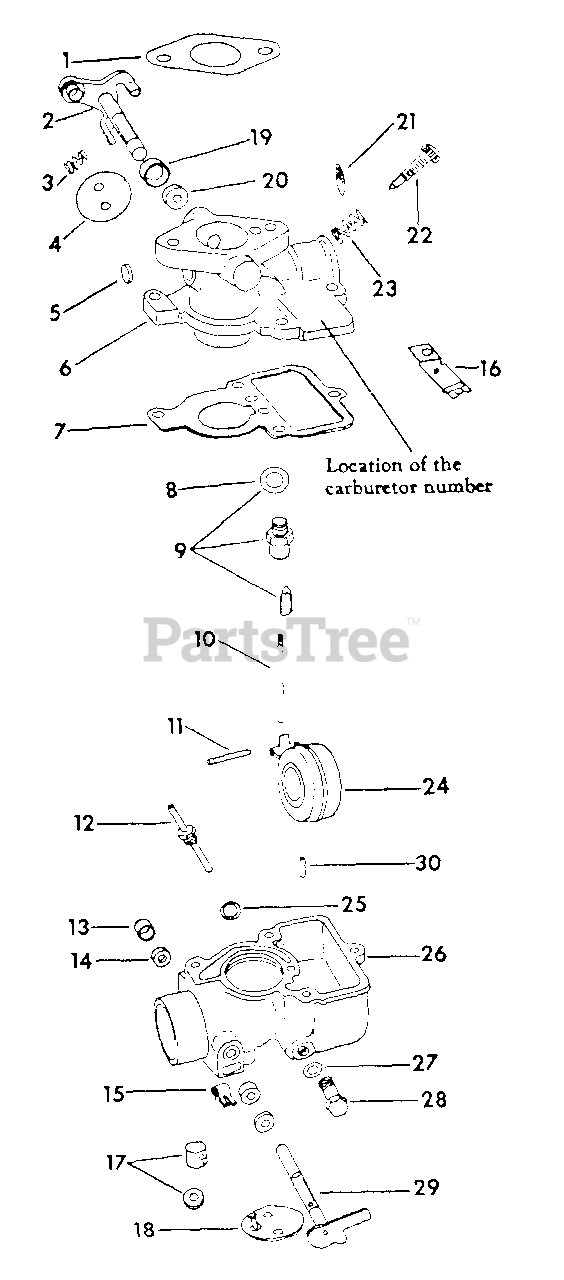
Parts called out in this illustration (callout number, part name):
1	GASKET, CARBURETOR
2	LEVER AND SHAFT ASSY, THROTTLE
3	SPRING, IDLE SET SCREW RETAINER
4	BUTTERFLY, THROTTLE
5	PLUG, THROTTLE BODY EXPANSION
6	BODY ASSY, THROTTLE
7	GASKET, FUEL BOWL
8	GASKET, FLOAT NEEDLE VALVE CAGE
9	CAGE ASSY, FLOAT NEEDLE VALVE
11	PIVOT, FLOAT LEVER
12	NOZZLE ASSY, DISCHARGE
13	RETAINER, STARTING SHUTTER SHAFT DUST
14	SEAL, BUTTERFLY SHAFT DUST
15	SPRING, STARTING SHUTTER FRICTION
16	BRACKET, CHOKE
17	PACKAGE, DRIP HOLE FILLER REPLACEMENT
18	SHUTTER ASSY, STARTING
19	RETAINER, BUTTERFLY SHAFT DUST SEAL
20	SEAL, STARTING SHUTTER SHAFT DUST
21	SCREEN, STRAINER
22	SCREW, IDLE ADJUSTING
23	SPRING, IDLE ADJUSTING SCREW RETAINER
24	FLOAT AND LEVER ASSY
25	GASKET, DISCHARGE NOZZLE
26	BOWL ASSY, FUEL
27	GASKET, MAIN METERING JET
28	JET ASSY, MAIN METERING
29	SHAFT ASSY, CHOKE VALVE
30	BLEED, MAIN AIR
